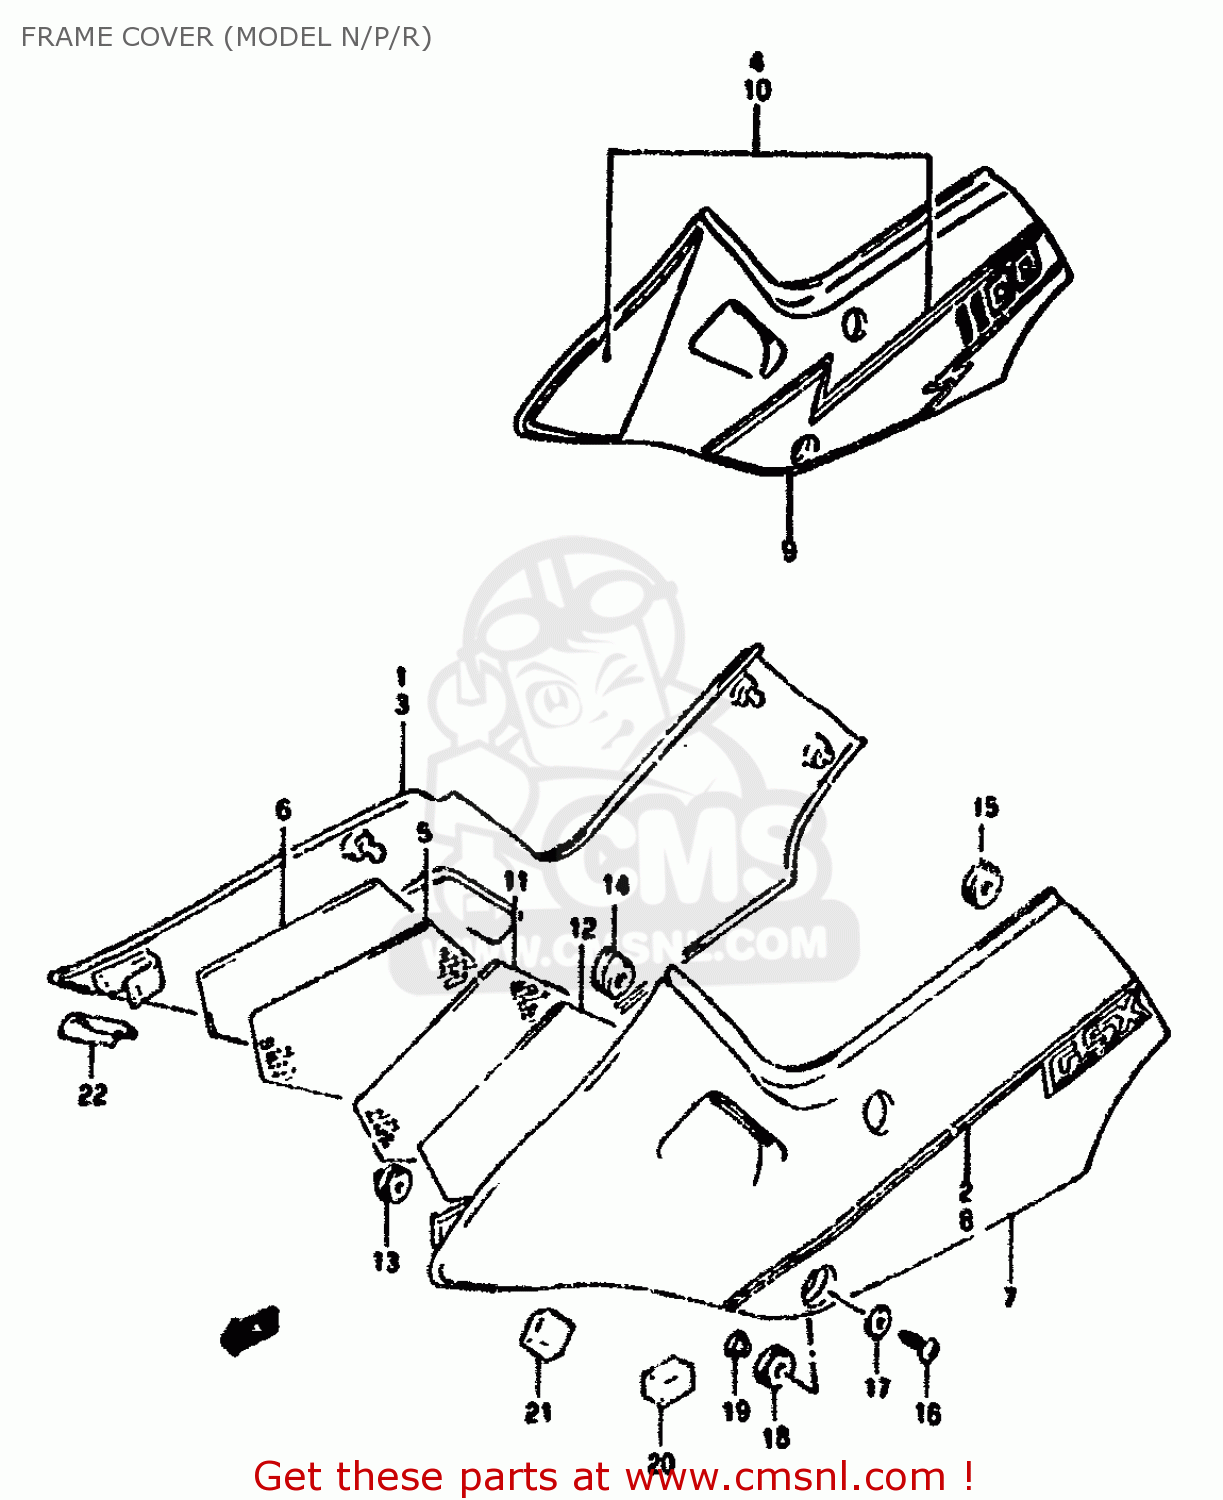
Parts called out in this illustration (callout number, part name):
1	COVER,FRAME,R
2	TAPE,FRAME COVER RH
3	COVER,FRAME RH (RED)
4	TAPE SET,RH
5	HEAT SHIELD,FRAME COVER
6	BALANCER,SEAT FRAME COVER
7	COVER,FRAME LH
8	TAPE,FRAME COVER LH
9	COVER,FRAME,L(RED)
10	TAPE SET,LH
11	HEAT SHIELD,FRAME COVER
12	BALANCER SHEET,FRAME C
13	CUSHION,COVER FRAME FR NO.1
14	CUSHION,COVER FRAME FR NO.2
15	CUSHION
16	SCREW(6X27)
17	WASHER(6.5X18X1.6)
18	CUSHION,SEAT TAIL COVER SIDE
19	WASHER
20	WASHER(6.5X18X1.6)
21	WASHER
22	CUSHION,FRAME COVER
23	CUSHION
24	PROTECTOR,FRAME COVER FR
